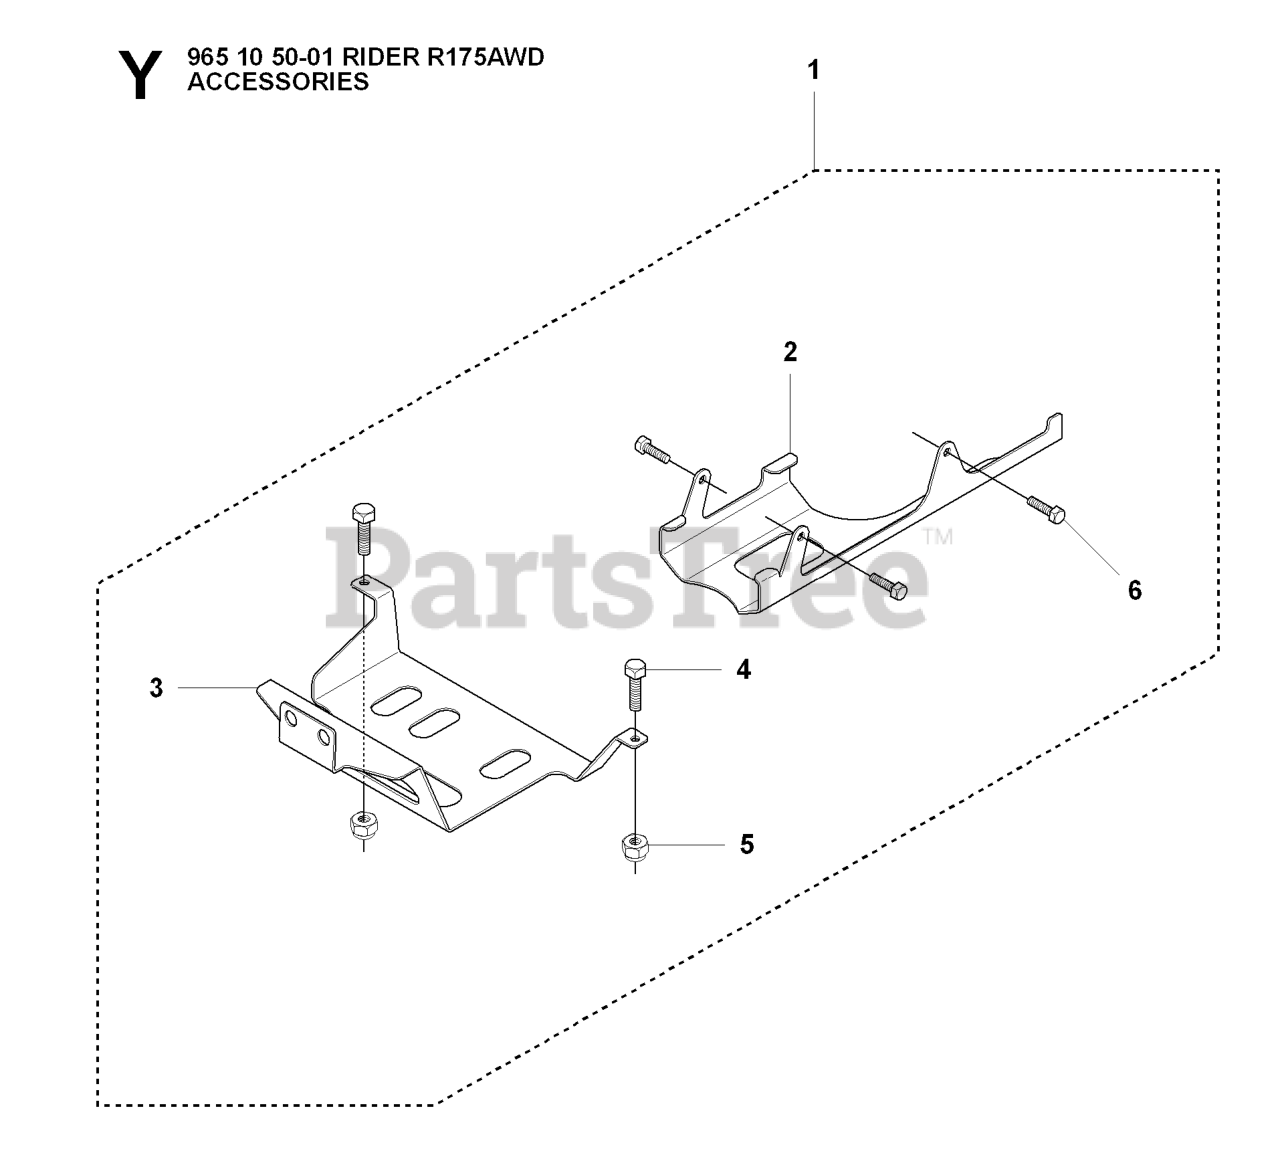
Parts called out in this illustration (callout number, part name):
1	AXLE PROTECTION KIT (R322T)
3	RP PROTECTION PLATE REAR
5	LOCKNUT M8
6	BOLT FLANGE - M8X16
